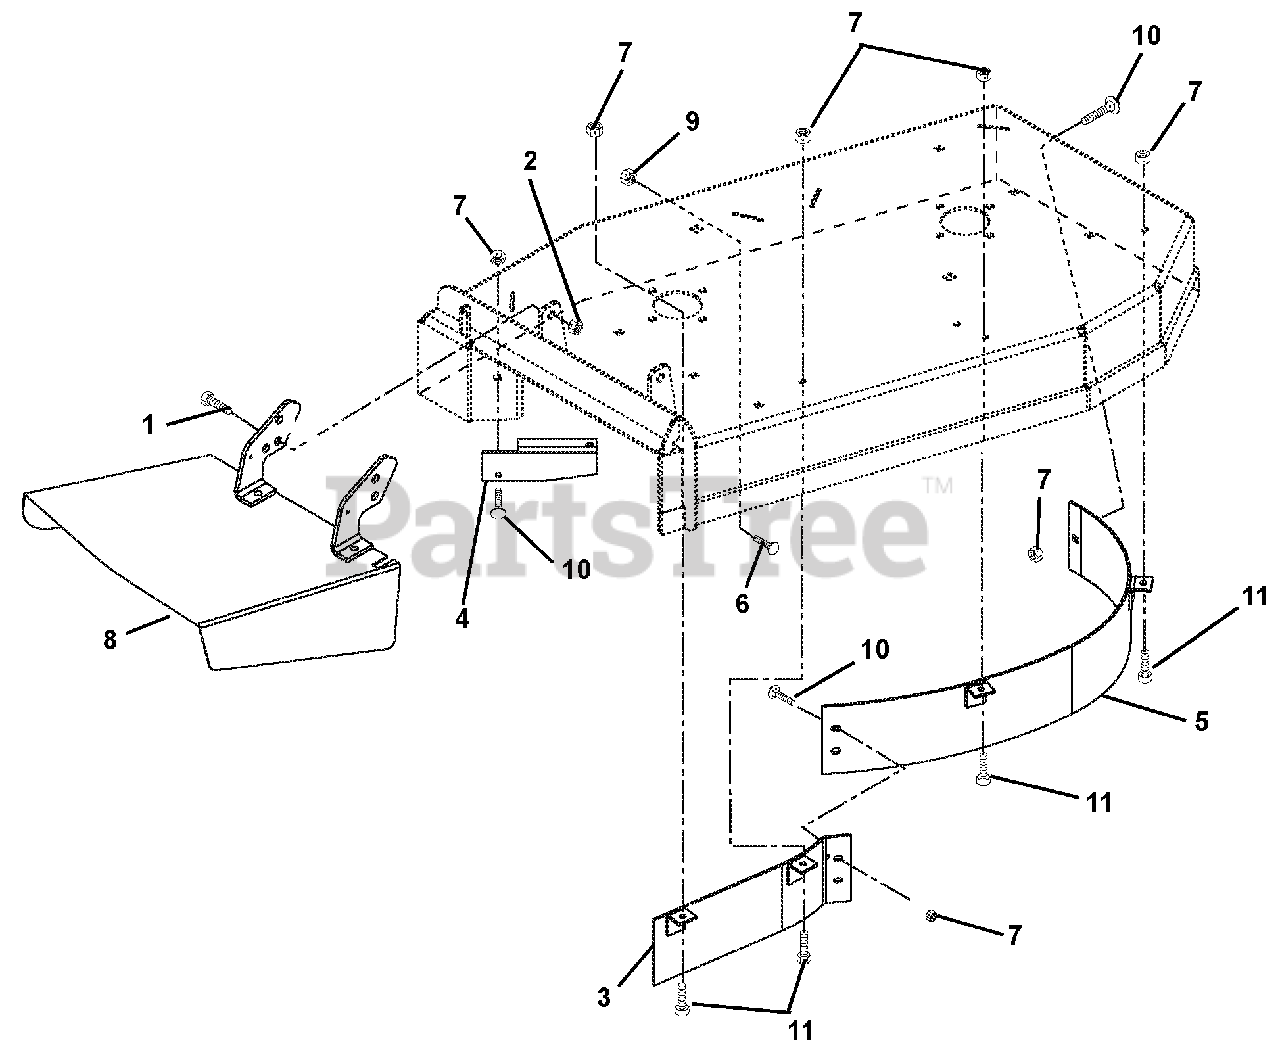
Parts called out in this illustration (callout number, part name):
1	Bolt-Hex .50-13 x 1.25 Grade 5
2	Nut-Locking-Nylon .50-13
3	Weldment- Upper Baffle Right
4	Deflector 32"
5	Weldment- Upper Baffle Left
6	Bolt-Round Head Square Neck .38-16 x 1.00 Grade 5
7	Nut-Locking-Top-Flange .31-18
8	Chute-Discharge
9	Nut-Locking-Top-Flange .38-16
10	Bolt-Round Head Square Neck .31-18 x .75 Grade 5
11	Bolt-Hex .31-18 x .75 Grade 5
